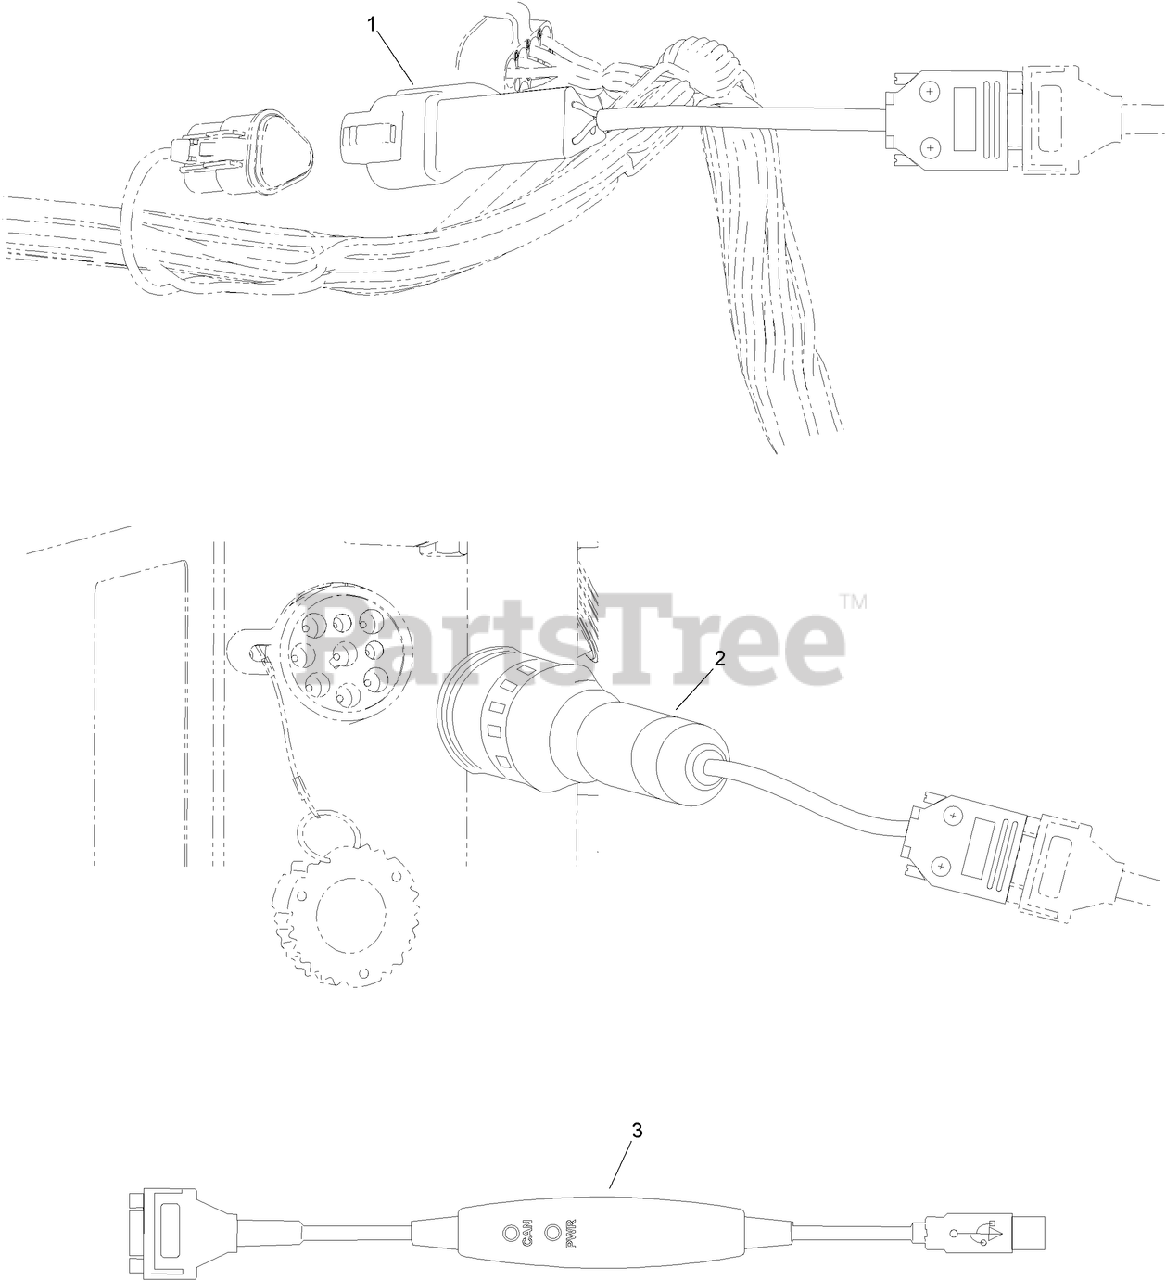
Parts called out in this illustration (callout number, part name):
1	CABLE-CAN-BUS,W/DEUTSCH 3PIN
2	CABLE-CAN-BUS,W/DEUTSCH 9PIN
3	USB CAN Gateway
